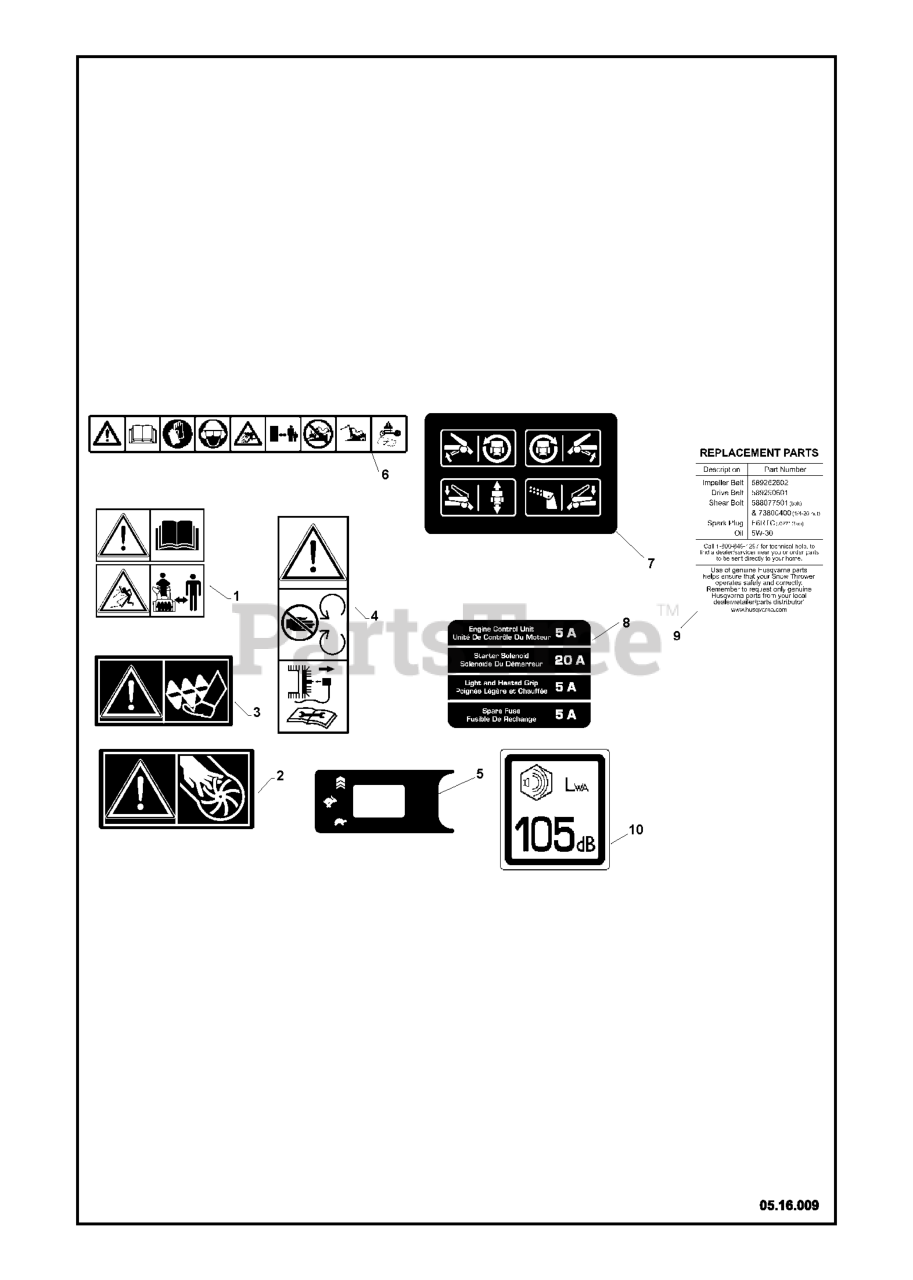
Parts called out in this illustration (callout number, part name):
1	DECAL.AUGER."
2	DECAL.CHUTE.SAFETY.EU/SC.17
3	DECAL.AUGER.SAFETY.
4	DECAL.BELT.GUARD.
5	DECAL SNOW CONSOLE GRAPHIC DEC
7	DECAL SNOW CONSOLE GRAPHIC DEC
8	DECAL SNOW BATTERY BOX GRAPHIC
9	DECAL SNOW BATTERY BOX GRAPHIC
10	DECAL.NOISE.LEV.105/CE.EAC.UKR
